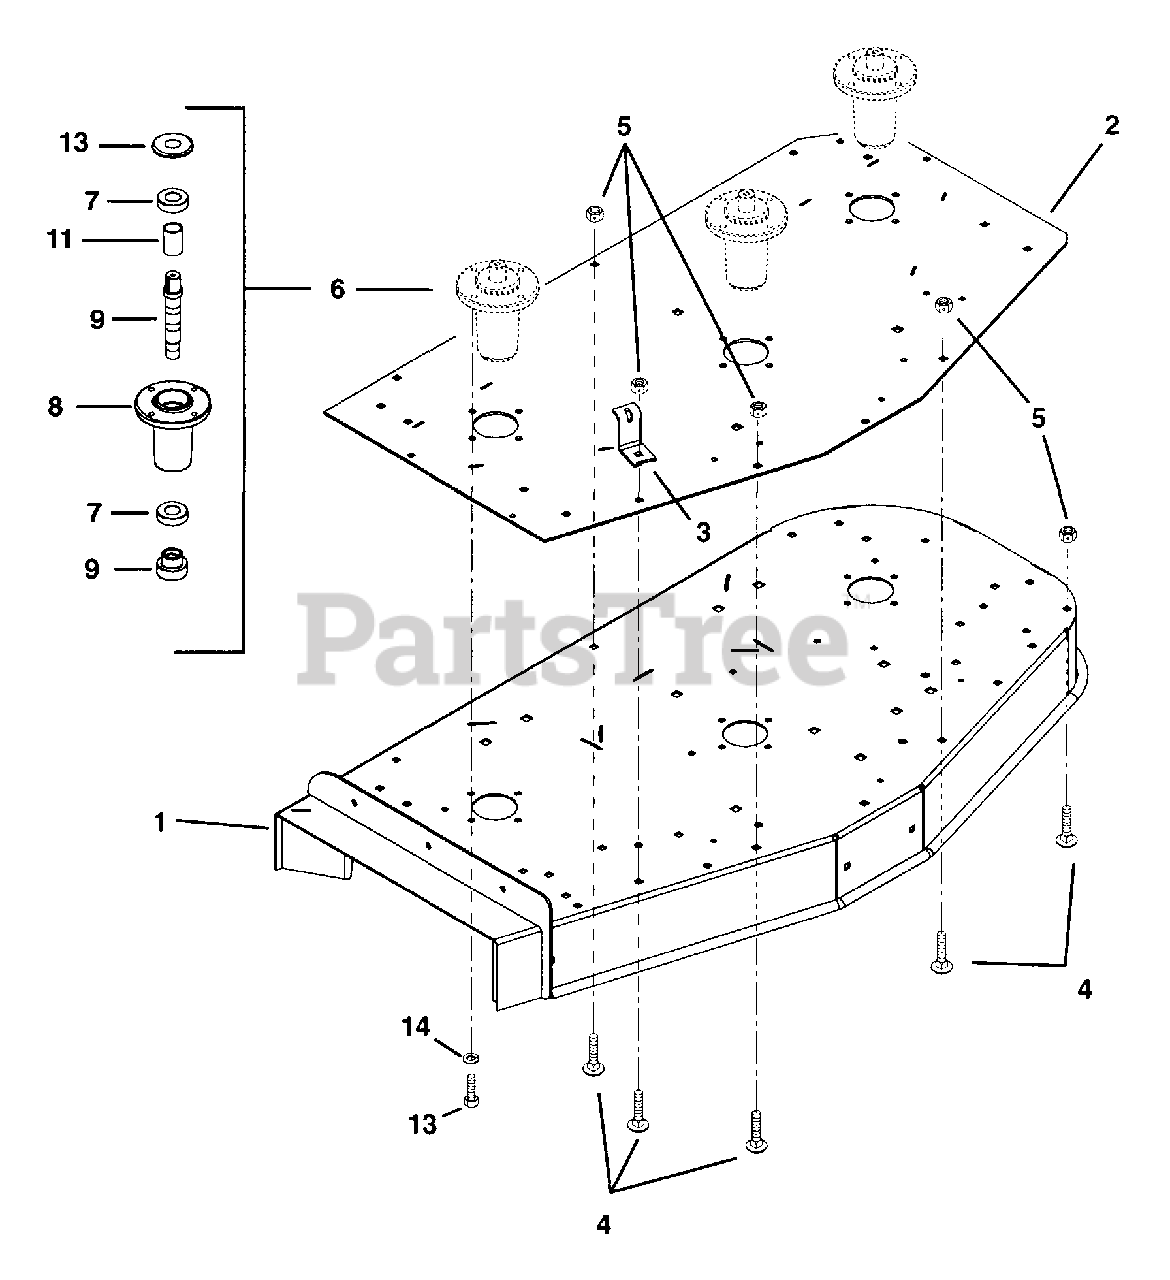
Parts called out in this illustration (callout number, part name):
1	Weldment, 50" Deck (Side Discharge)
2	Plate, 50" Reinforcement
3	Anchor, Spring
4	Bolt-Round Head Square Neck .38-16 x 1.25 Grade 2
5	Nut-Locking-Nylon .38-16
6	Assembly, Spindle L-Hub
7	Bearing-Wide Inner Ring 1.00 x 2.0467
8	Housing-Bearing
9	Shaft-Spindle
11	Spacer 1.010 x 1.250 x 1.845
12	Slinger-Dust
13	Bolt-Hex .38-16 x 1.00 Grade 5
14	Washer-Locking .38 x .094
